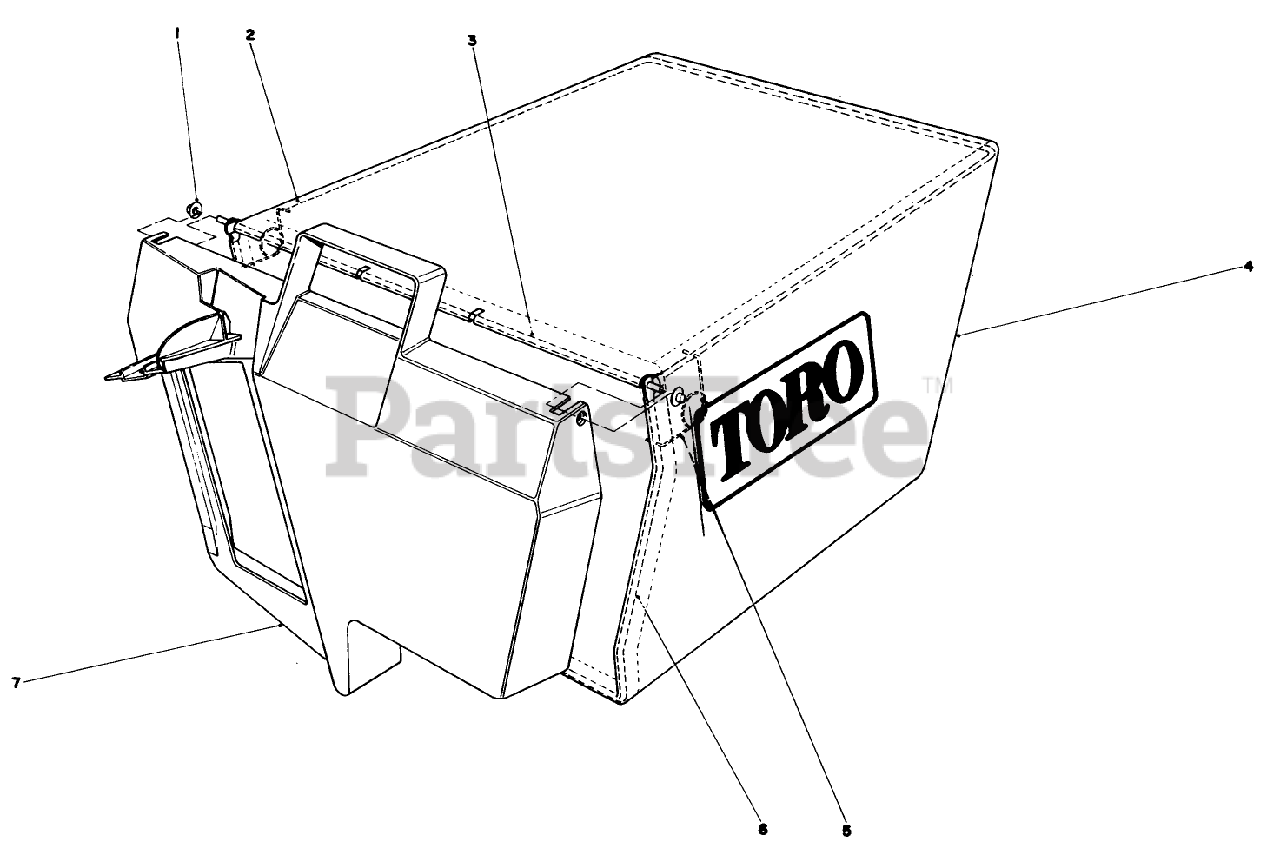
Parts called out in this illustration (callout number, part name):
1	NUT-PUSH
3	HingeBag Door
5	SPRING
